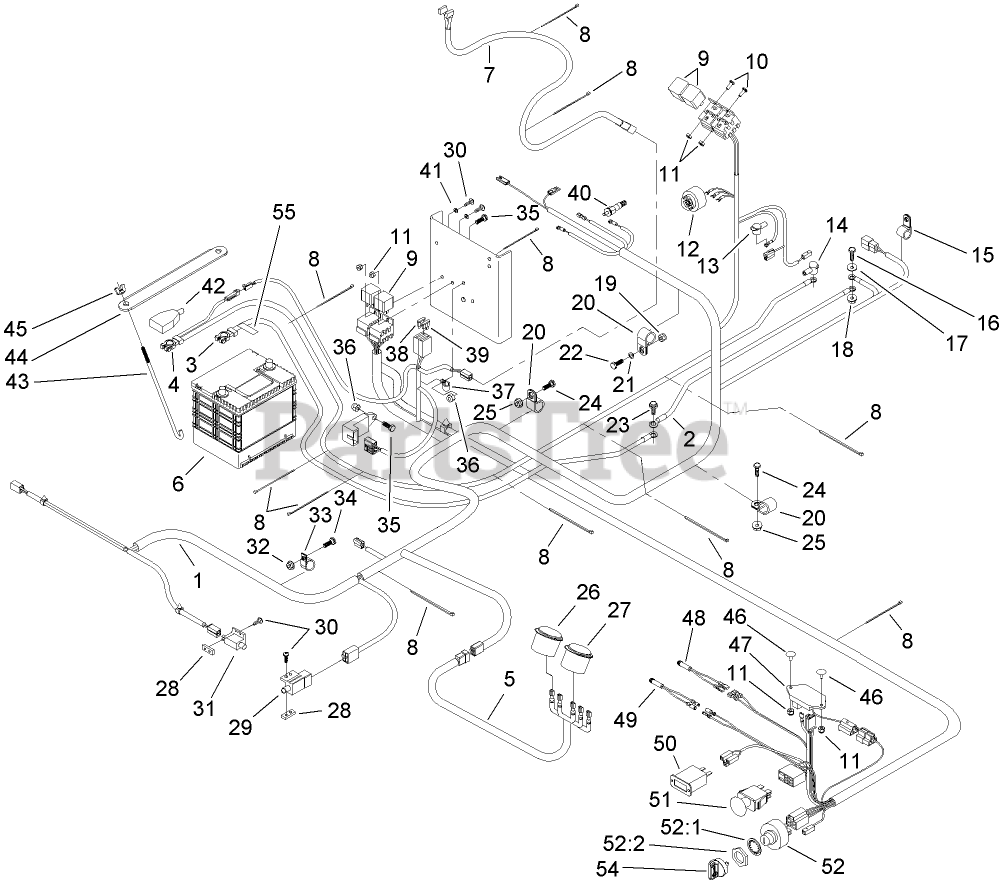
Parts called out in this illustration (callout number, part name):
1	HARNESS-WIRE
2	CABLE-ENGINE NEGATIVE
3	CABLE-BATTERY NEGATIVE
4	CABLE-STARTER
5	HARNESS-GAUGE
6	BATTERY-DRY
7	HARNESS-WIRING, SEAT
8	TIE-PLASTIC
11	NUT-LOCK, NI
12	ALARM-TONE, DUAL
13	CAP-INSULATOR, RED
14	INSULATOR-STARTER
15	CLIP-LOOM
16	SCREW-HH
17	WASHER-FLAT
18	NUT-HHF, WHIZ
19	NUT-LOCK
20	CLIP-LOOM
21	WASHER-FLAT
22	SCREW-HH
23	SCREW-HWHTF
24	SCREW-HH
25	NUT-HF
26	GAUGE-VOLTMETER
27	GAUGE-TEMPERATURE
28	PLATE-TAPPED
29	SWITCH
30	SCREW-PPH
31	SWITCH-OPEN, NORMALLY
32	NUT-HF
33	CLIP-LOOM
34	SCREW-HH
35	SCREW-HH
36	NUT-LOCK, NI
37	CLIP-LOOM
38	FUSE-BLADE TYPE, 20 AMP
39	FUSE-40 AMP
40	SENDER-TEMPERATURE
41	WASHER-FLAT
42	INSULATOR-TERMINAL, BATTERY
43	Bolt-Holddown
44	HOLDDOWN-BATTERY
45	WINGNUT
46	BOLT-CARR
47	MODULE-DELAY, SEAT
48	INDICATOR-LED, RED
49	INDICATOR-LED, AMBER
50	METER-HOUR
51	SWITCH-PTO
52	SWITCH ASM
52:1	NUT-HH
52:2	WASHER-TOOTH, INTERNAL
54	KEY-IGNITION
55	DECAL-INSTRUCTIONS, CHARGING
